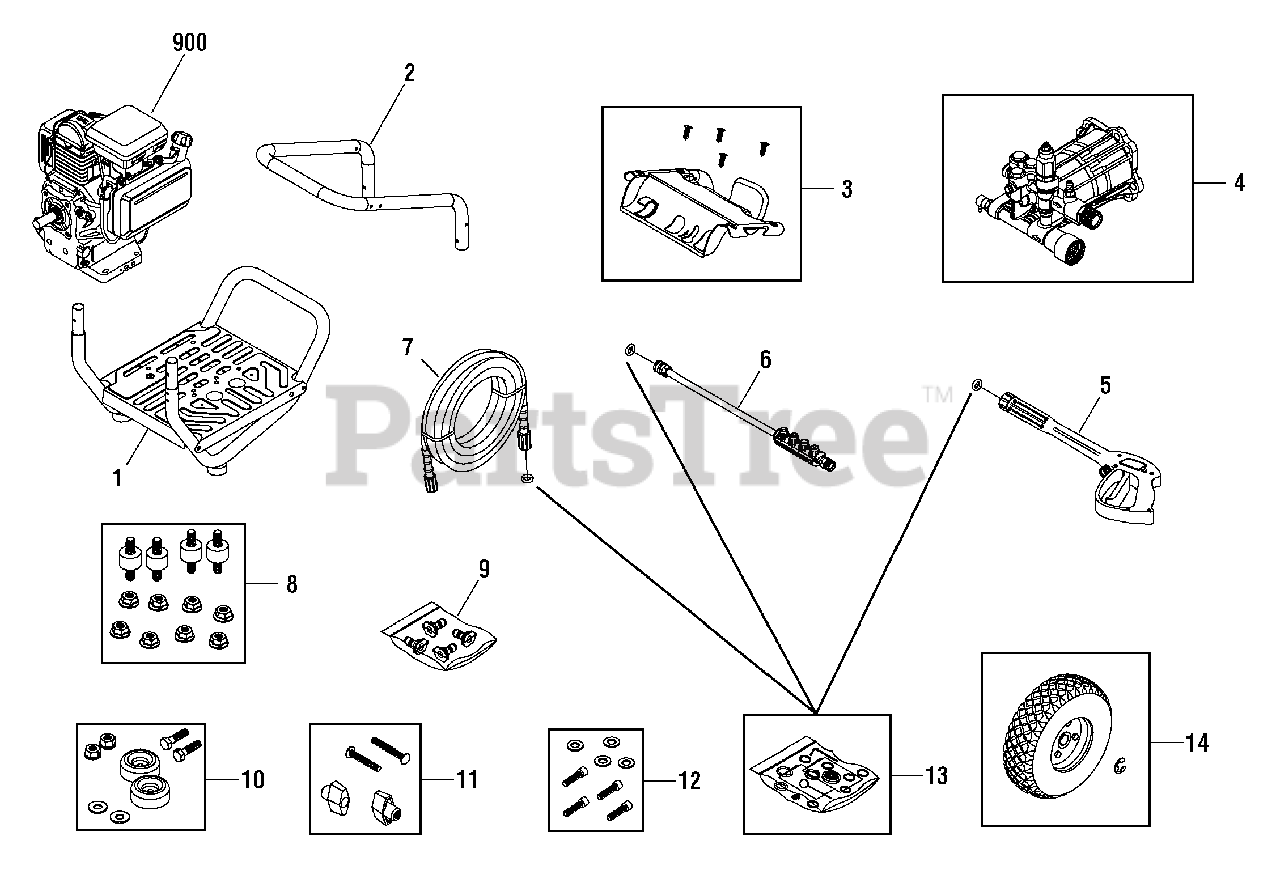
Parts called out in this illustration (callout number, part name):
4	PUMP
5	GUN
6	EXTENSION, QC
7	HOSE
8	KIT, Vibration Mount
9	KIT, QC Nozzles
10	MOUNT, Vibration
11	KIT, Hardware, Handle
12	KIT, Hardware, Pump Mounting
13	KIT, O-Ring
900	* ENGINE
